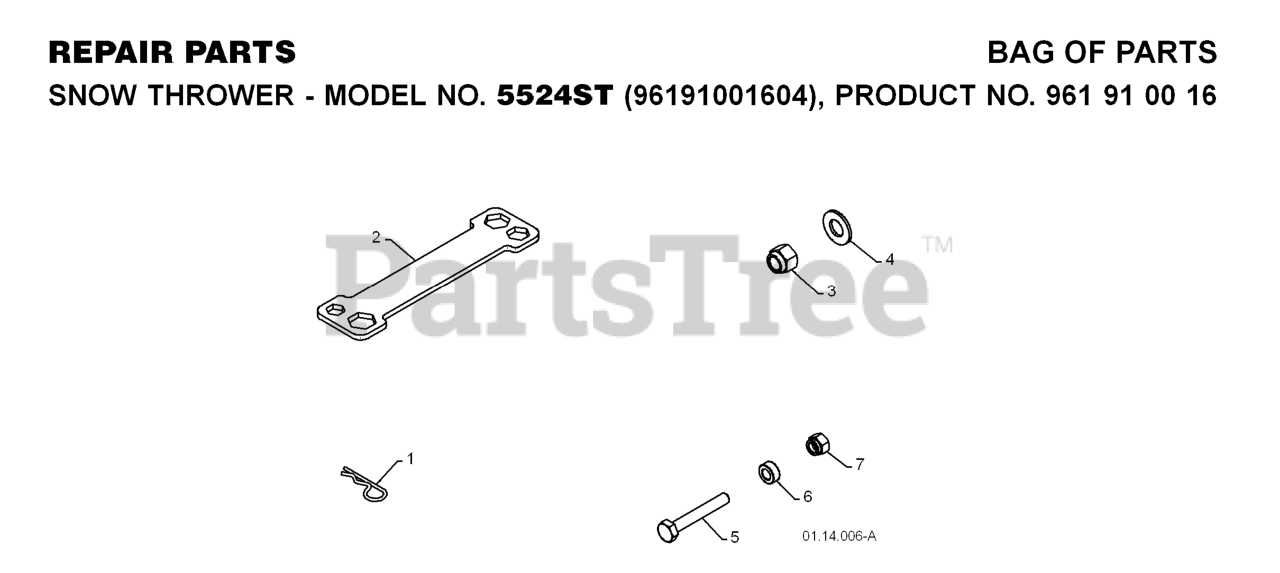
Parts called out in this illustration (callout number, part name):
1	SPRING RETAINER
2	RP WRENCH, SNOWTHROWER
3	NUT
4	WASHER
5	BOLT, SHEAR
6	SPACER.3943.SLEEVE.250X.47
7	LOCKNUT.NYLOC.1/4-20
